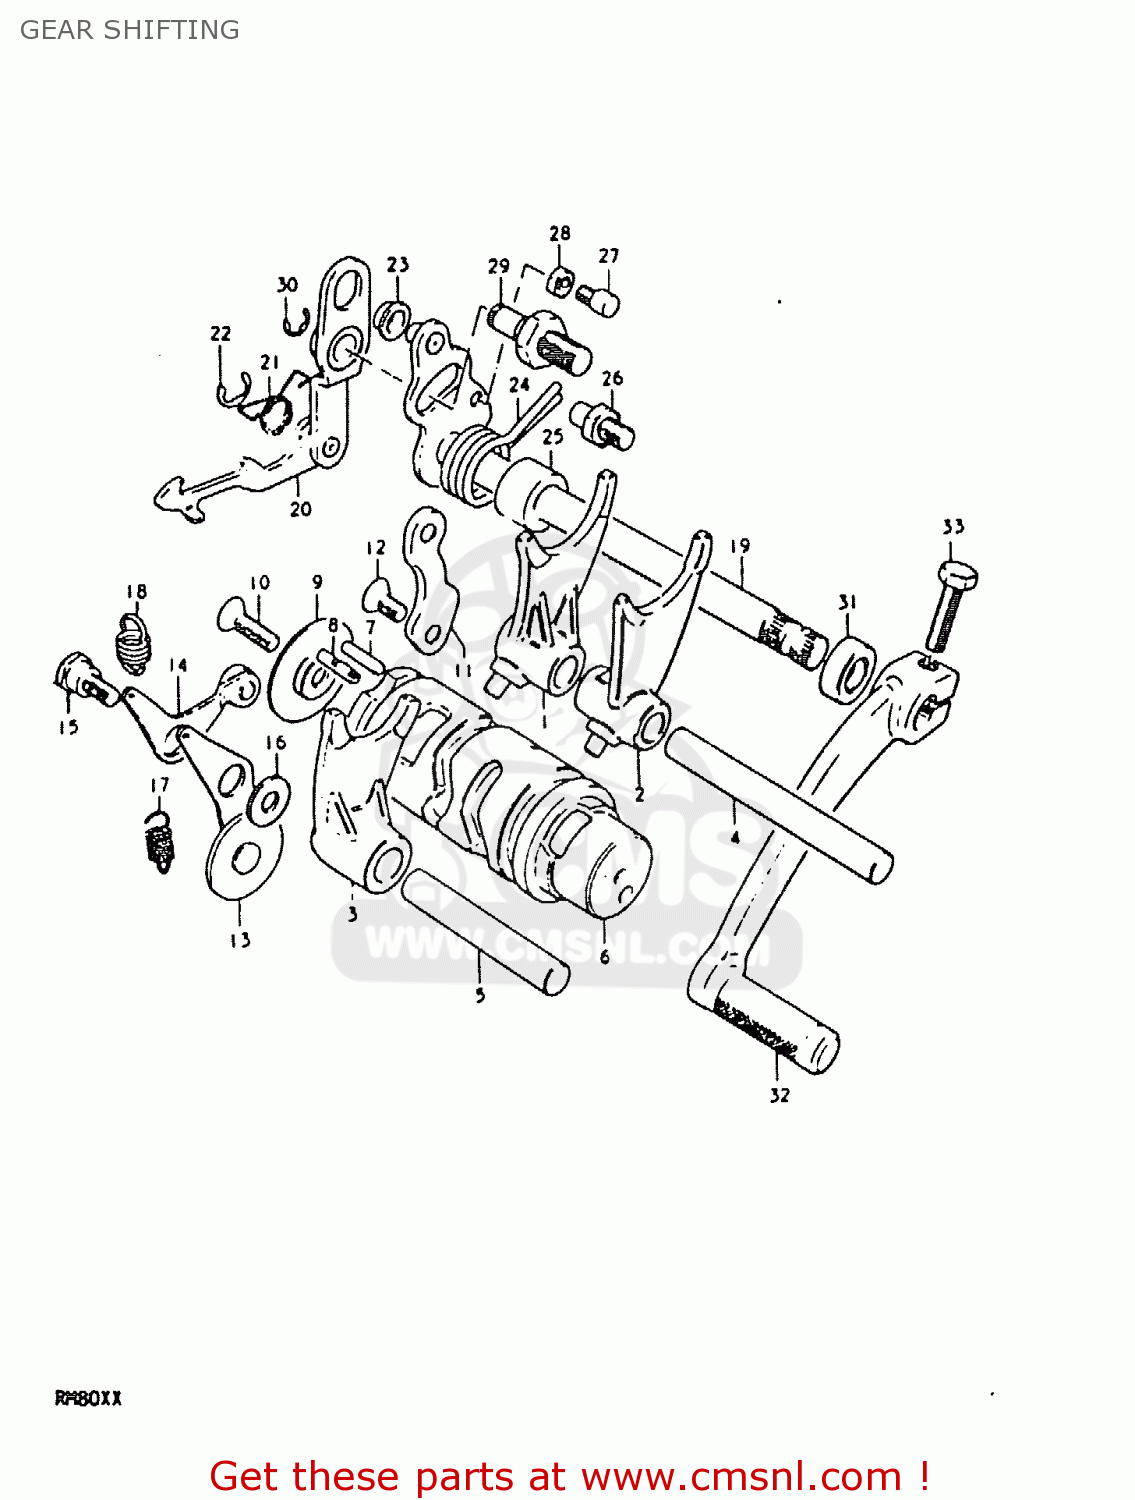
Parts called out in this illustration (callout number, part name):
1	FORK,GEAR SHIFT NO.1
2	FORK,GEAR SHIFT NO.2
3	FORK,GEAR SHIFT NO.2
4	SHAFT,GEAR SHIFT FORK
5	SHAFT,GEAR SHIFT FORK
6	CAM,GEAR SHIFT
7	PIN(4X15.8)
8	PIN
9	RETAINER,GEAR SHIFT CAM
10	SCREW
11	GUIDE,GEAR SHIFTING CABLE
12	SCREW
13	STOPPER,SHIFT CAM
14	STOPPER,GEAR SHIFT CAM
15	BOLT(6X18.3)
16	WASHER (6.5X13X2.3)
17	SPRING
18	SPRING
19	SHAFT,GEAR SHIFT
20	PAWL,GEAR SHIFTING
21	SPRING
22	E RING
23	SPACER(7X10X5)
24	SPRING
25	SPACER(12X20X15.3)
26	STOPPER,GEAR SHIFT CAM
27	BOLT,GEAR SHAFT RETURN SPR SET
28	NUT 6MM
29	STOPPER,GEAR SHIFT CAM
30	E RING 6MM
31	OIL SEAL
32	LEVER ASSEMBLY,GEAR SHIFTING
33	BOLT
